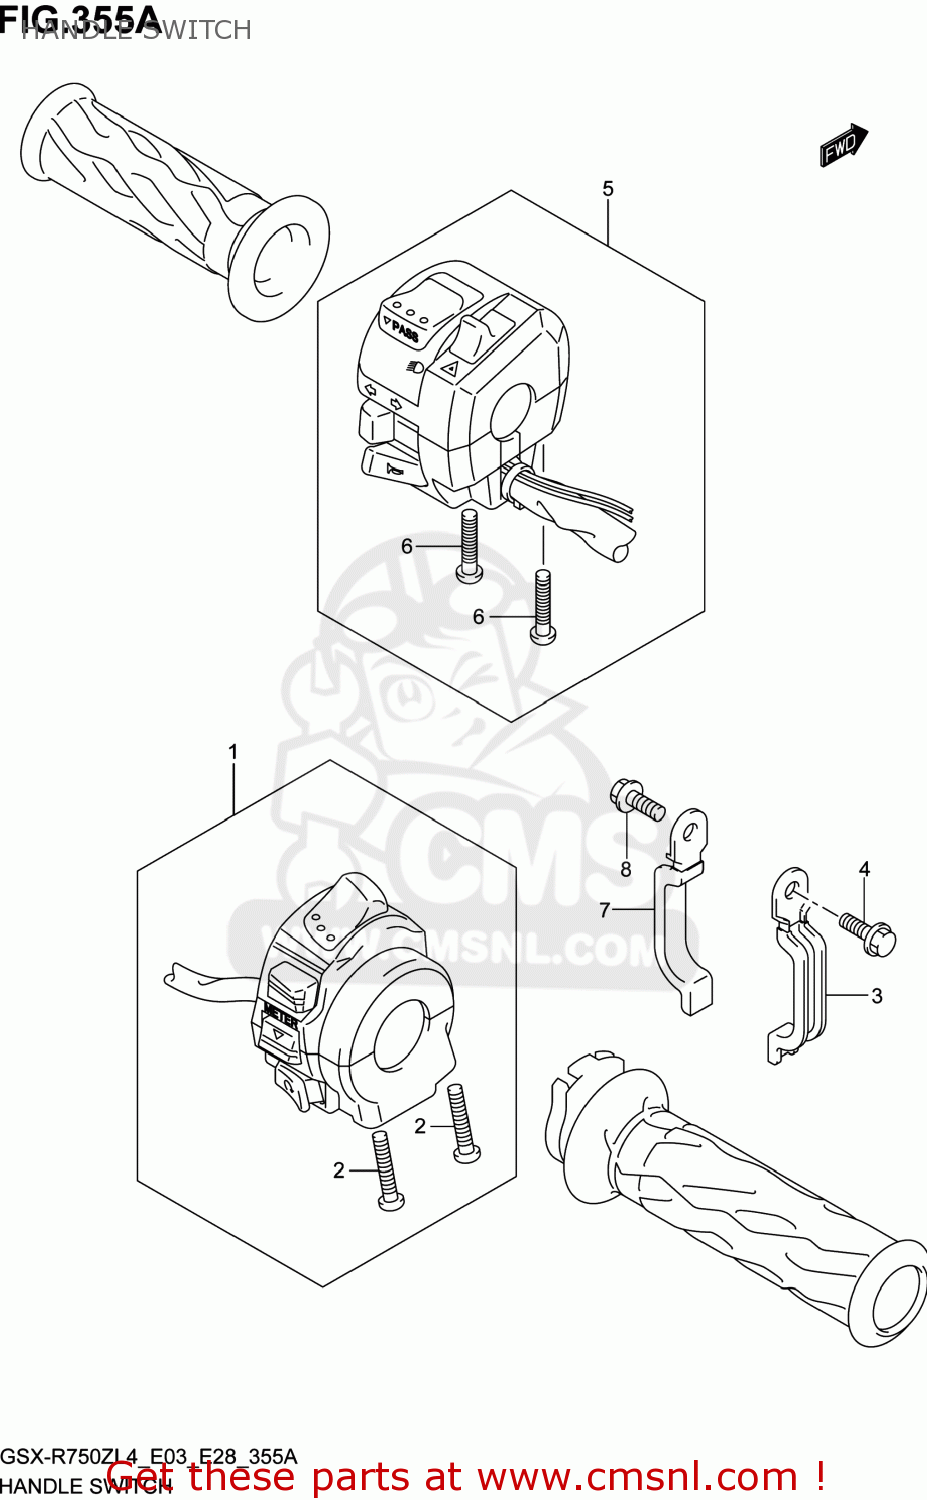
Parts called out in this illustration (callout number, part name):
1	SWITCH ASSY,HANDLE,R
2	SCREW
3	CLAMP
4	BOLT
5	SWITCH ASSY,HANDLE,L
6	SCREW
7	CLAMP
8	BOLT
